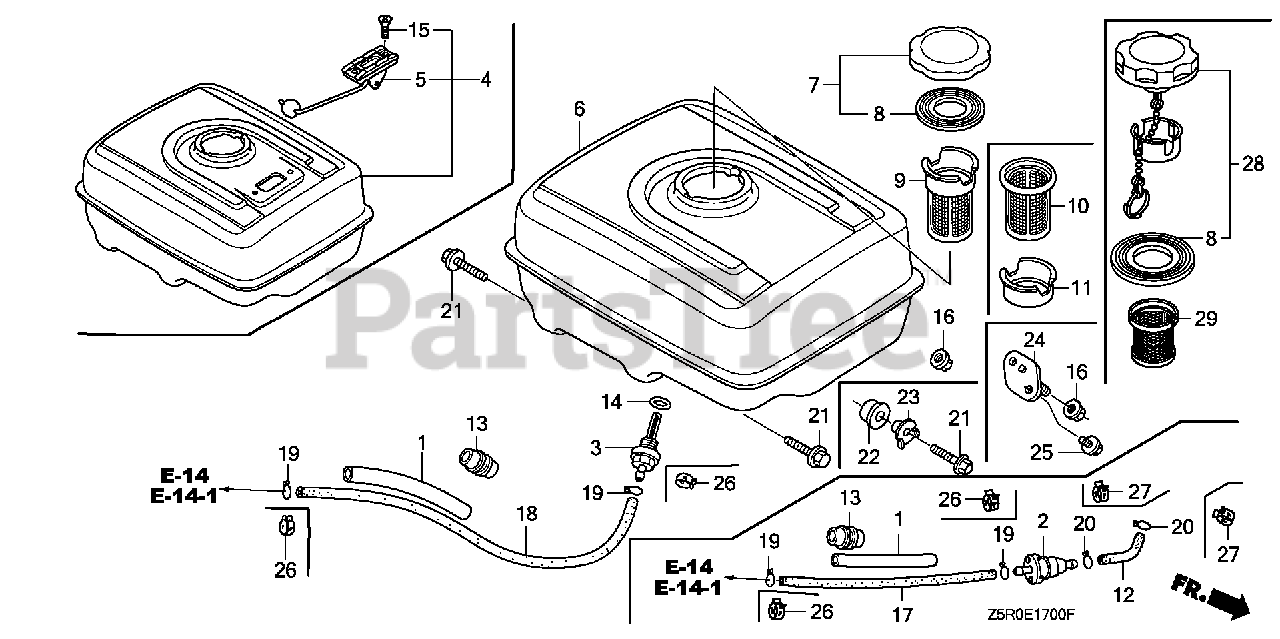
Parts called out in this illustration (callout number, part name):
1	RUBBER, SUPPORTER (107MM)
3	JOINT, FUEL TANK
6	TANK, FUEL *NH31* (MCKINLEY WHITE)
6	TANK, FUEL *NH1* (BLACK)
7	CAP, FUEL FILLER (CHROME PLATED)
8	GASKET, FUEL FILLER CAP (39X62X3) (RADICON)
8	GASKET, FUEL FILLER CAP (39X62X3) (TOUYOUSYA)
8	GASKET, FUEL FILLER CAP (39X62X3)
14	O-RING (13.5X1.5) (ARAI)
14	O-RING (14MM) (NOK)
16	NUT, FLANGE (8MM)
18	TUBE, FUEL (4.5X235) (FKM)
18	BULK HOSE, FUEL (4.5X3000) (4.5X235)
19	CLIP, TUBE (B8)
21	BOLT, FLANGE (8X25)
26	CLAMP, TUBE (D8)
28	CAP, FUEL FILLER (CHROME PLATED)
28	CAP, FUEL FILLER
